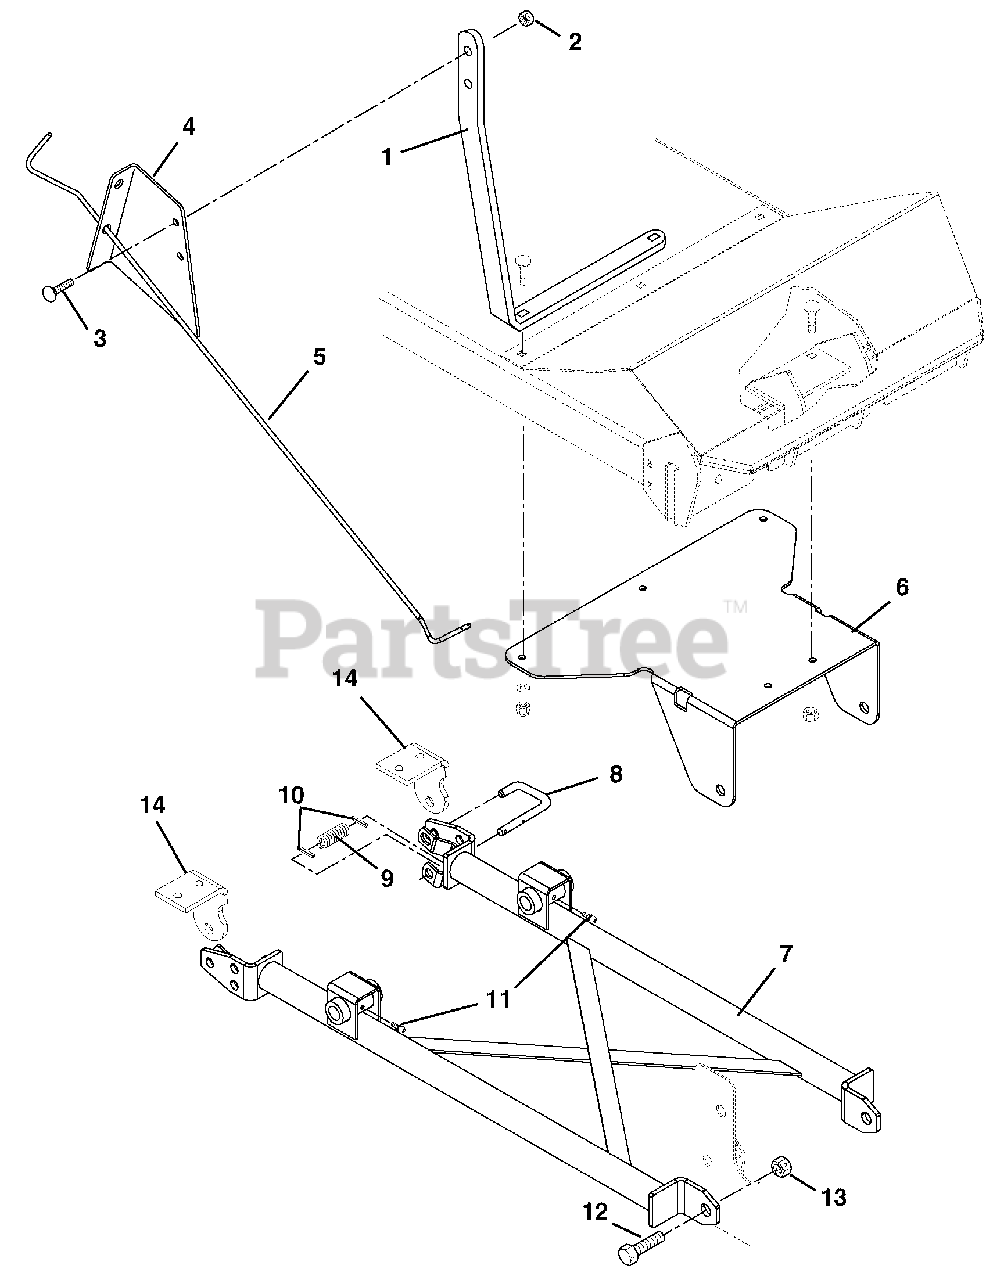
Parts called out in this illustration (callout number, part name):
1	Control Support
2	Nut-Locking-Center .38-16
3	Bolt-Round Head Square Short Neck .38-16 x .75
4	Control Bracket
5	Rod, Control
6	Hanger Bracket
7	Support Weldment
8	Latch Pin
9	Spring-Compression .058 x .65 x 2.13
10	Pin-Roll .125 x .75
11	Fitting-Lube .25-28 x .256
12	Bolt-Hex .62-11 x 1.50 Grade 5
13	Nut-Locking-Center .62-11 Grade 2
14	Rear Bracket
